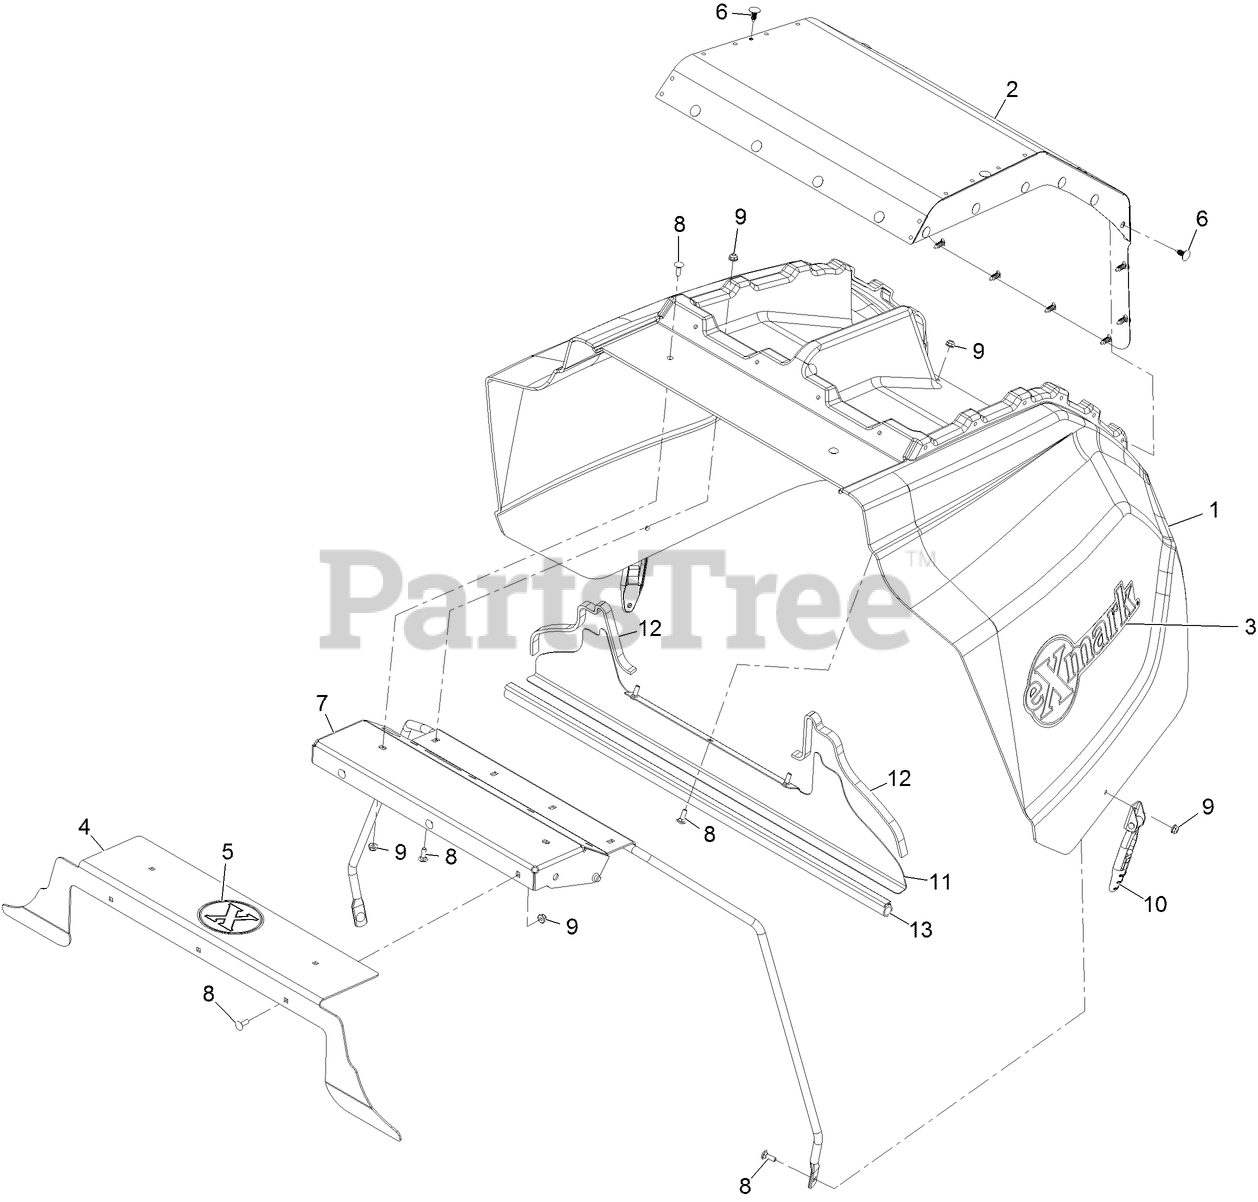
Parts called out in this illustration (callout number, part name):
1	HOOD,LZSD
2	Screen-Intake
3	DECAL-EXMARK
4	Block Off-Hood
5	DECAL-X-LOGO
6	PLUG-PLASTIC
7	SUPPORT-HOOD
8	BOLT-CARR
10	LATCH-RUBBER
11	Plate-Seal
12	SEAL-FOAM
13	Seal-Bulb
